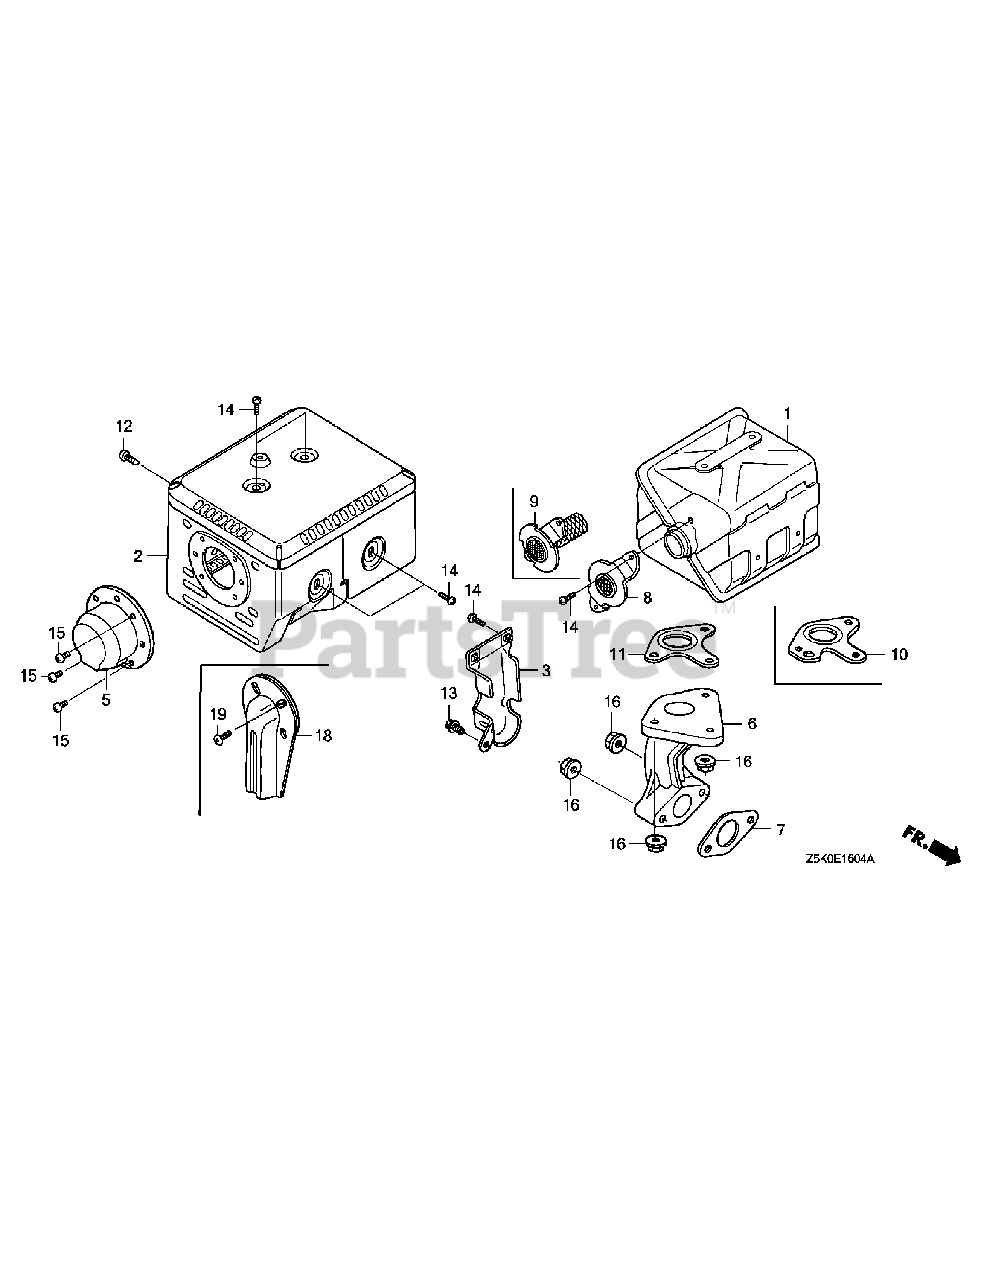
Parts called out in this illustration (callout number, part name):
1	Muffler Comp.
2	Protector Comp., Muffler
3	Protector, Ex. Pipe
5	Cap, Muffler
7	Gasket, Ex. Pipe
8	Flange Comp., Baffle
9	Arrester Comp., Spark
10	Gasket, Muffler(Arrester)(Nippon Leakless)
11	Gasket, Muffler(Thai Leakless)
12	Screw, Tapping, 6X10
13	Bolt, Flange, 6X12(Ct200)
14	Screw, Tapping, 5X8
15	Screw, Tapping, 4X6
16	Nut, Flange, 8Mm
18	Deflector Comp., Muffler
19	Screw, Tapping, 4X6
